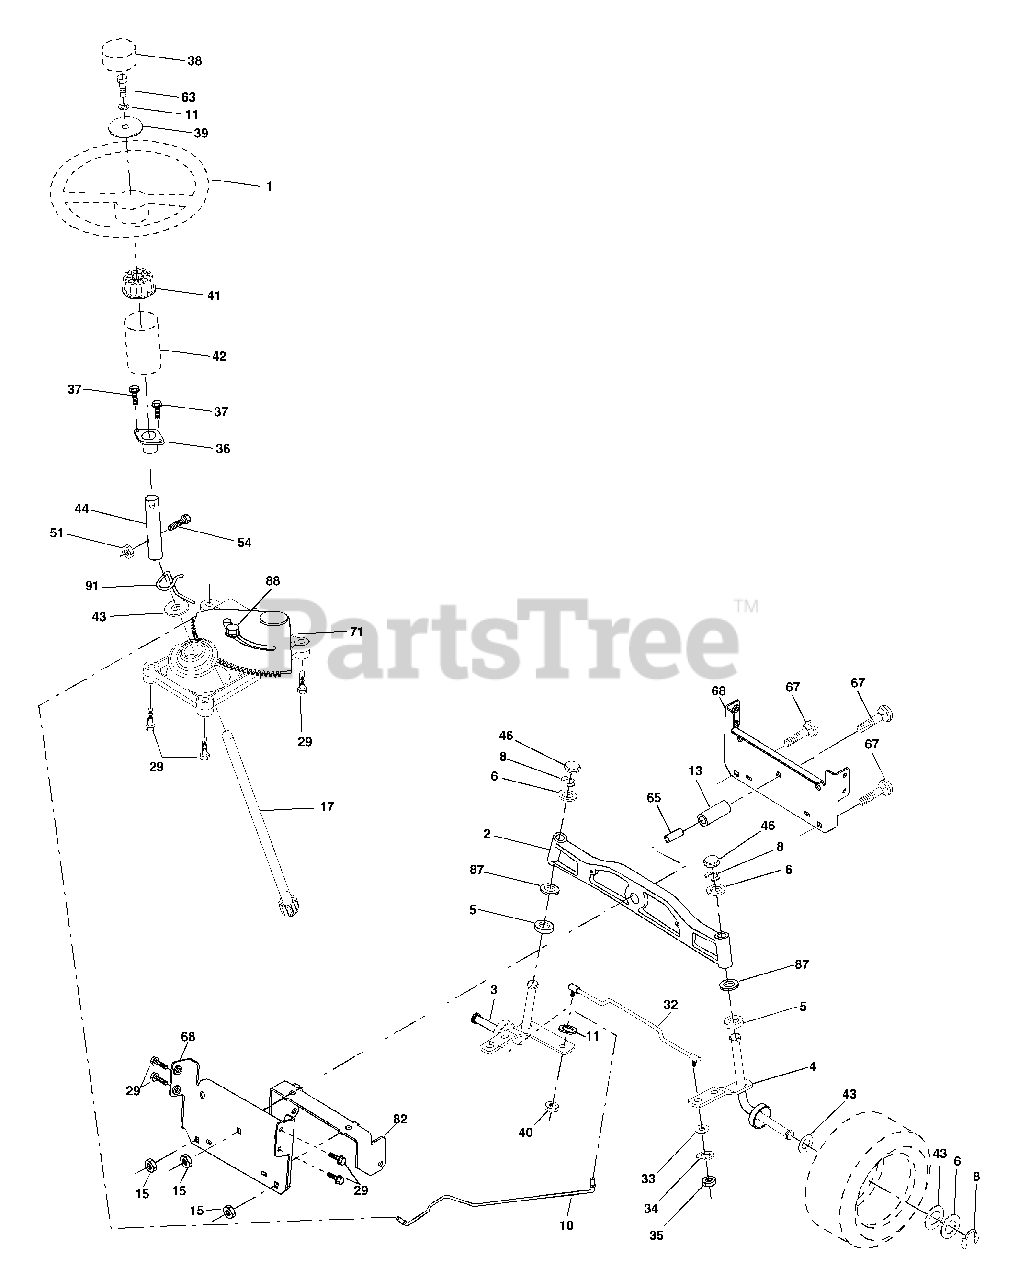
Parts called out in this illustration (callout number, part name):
1	Wheel Steering
2	Axle Asm Cast Iron LT
3	Spindle Asm LH
4	Spindle Asm RH
5	Bearing Race Thrust Harden
6	Washer 25/32 X 1-5/8 X 16 Ga
8	Ring Klip #t5304-75
10	Link Drag
11	Washer Lock Hvy Hlcl Spr 3/8
13	Spacer Brg Axle Front
15	Nut Hex Flange Lock
17	Shaft Asm Strg
29	Screw 3/8-16 x .75
32	Rod Tie
33	Washer 11/32 x 3/4 x 16 Ga
34	Washer Lock Hvy Hlcl Spr 5/16
35	Crownlock Nut 5/16-24 Unf
36	Bushing Strg
37	Screw
38	Insert Cap Strg Wh
39	Washer 13/32 X 1-1/2 X 11 Ga
40	Lock nut
41	Adaptor Wheel Strg
42	Boot Steering Dash
43	Washer 25/32 X 1 1/4 X 16 Ga
44	Extension Steering Shaft LR/LT
46	Cap Spindle Fr Top Blk
51	Nut Lock Hex w/Ins 5/16-18
54	Bolt Fin Hex 5/16-18 Unc x 1-1/4
63	Bolt Fin Hex 3/8-16unc x 1 Gr. 5
65	Spacer Brace Axle
67	Bolt Rdhd Sq 3/8-16 Unc x 2-3/4
68	Axle, Brace
71	Steering Asm.
82	Bracket Susp Chassis Front
87	Washer Flat .781 x 1 1/2 x .14
88	Bolt Shoulder 7/16-20
91	Clip Steering
